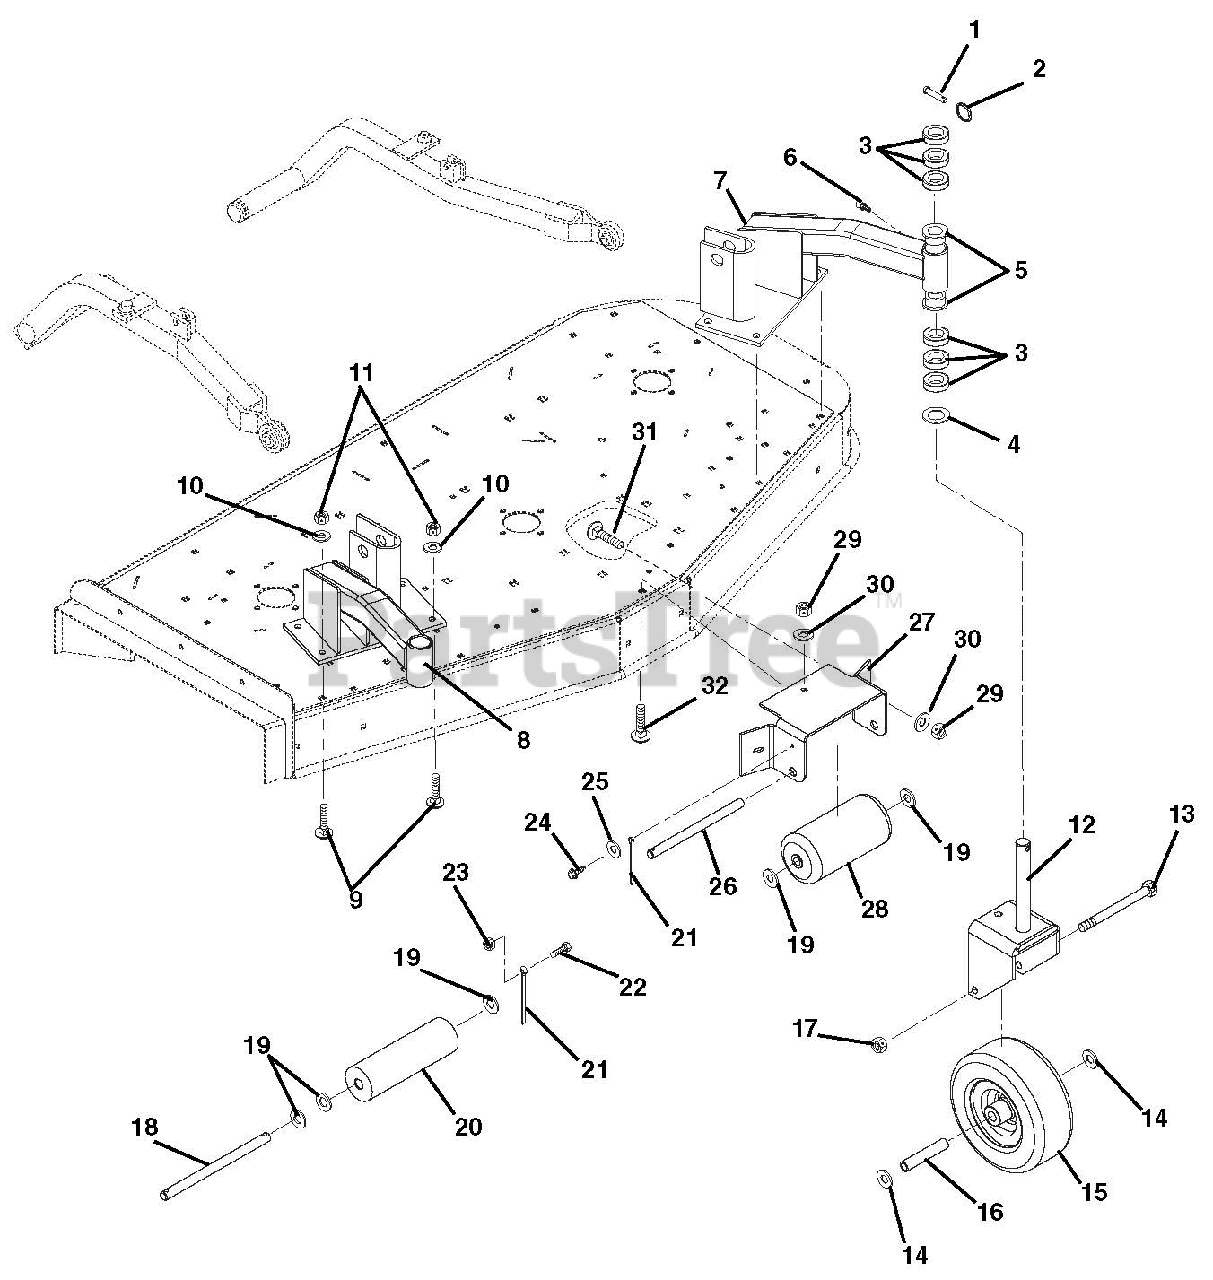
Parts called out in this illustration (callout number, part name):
1	Pin-Clevis .31 x 2.62 Grade 5
2	Ring-Retaining-External 1.062 x 1.25
3	Bushing-Sleeve 1.04 x 1.75 x .500
4	Washer-Hardened-Thrust 1.00 x 1.55 x .03
5	Bushing-Flange 1.020 x 1.385 x .75 x 1.75 Nylon
6	Fitting-Lube .25-28 x .256
7	Weldment, Wheel Mount - Left Hand
8	Weldment, Wheel Monut - Right Hand
9	Bolt-Round Head Square Neck .50-13 x 1.50 Grade 5
10	Washer-Flat-Steel .531 x 1.06 x .095
11	Nut-Locking-Nylon .50-13
12	Weldment, Caster Fork
13	Bolt-Hex .50-13 x 6.00 Grade 5
14	Washer-Hardened Thrust .760 x 1.25 x .094
15	Tire, 11.00 x 4.00
16	Spacer, .750 x .532 x 4.47
17	Nut-Locking-Center .50-16
18	Shaft, Center Roller
19	Washer-Flat-Steel .656 x 1.31 x .095
20	Roller, Gauge
21	Pin-Cotter .25 x 2.00
22	Bolt-Hex .25-20 x .75 Grade 5
23	Nut-Locking-Nylon .25-20
24	Screw-Self Tapping .25-20 x .50 x Hex Washer Head
25	Washer-Flat-Steel
27	Bracket, Anti-Scalp Roller
29	Nut-Locking-Nylon .38-16
30	Washer-Flat-Steel .406 x .812 x .065
31	Bolt-Round Head Square Neck .38-16 x 1.00 Grade 5
32	Bolt-Round Head Square Neck .38-16 x 1.25 Grade 5
